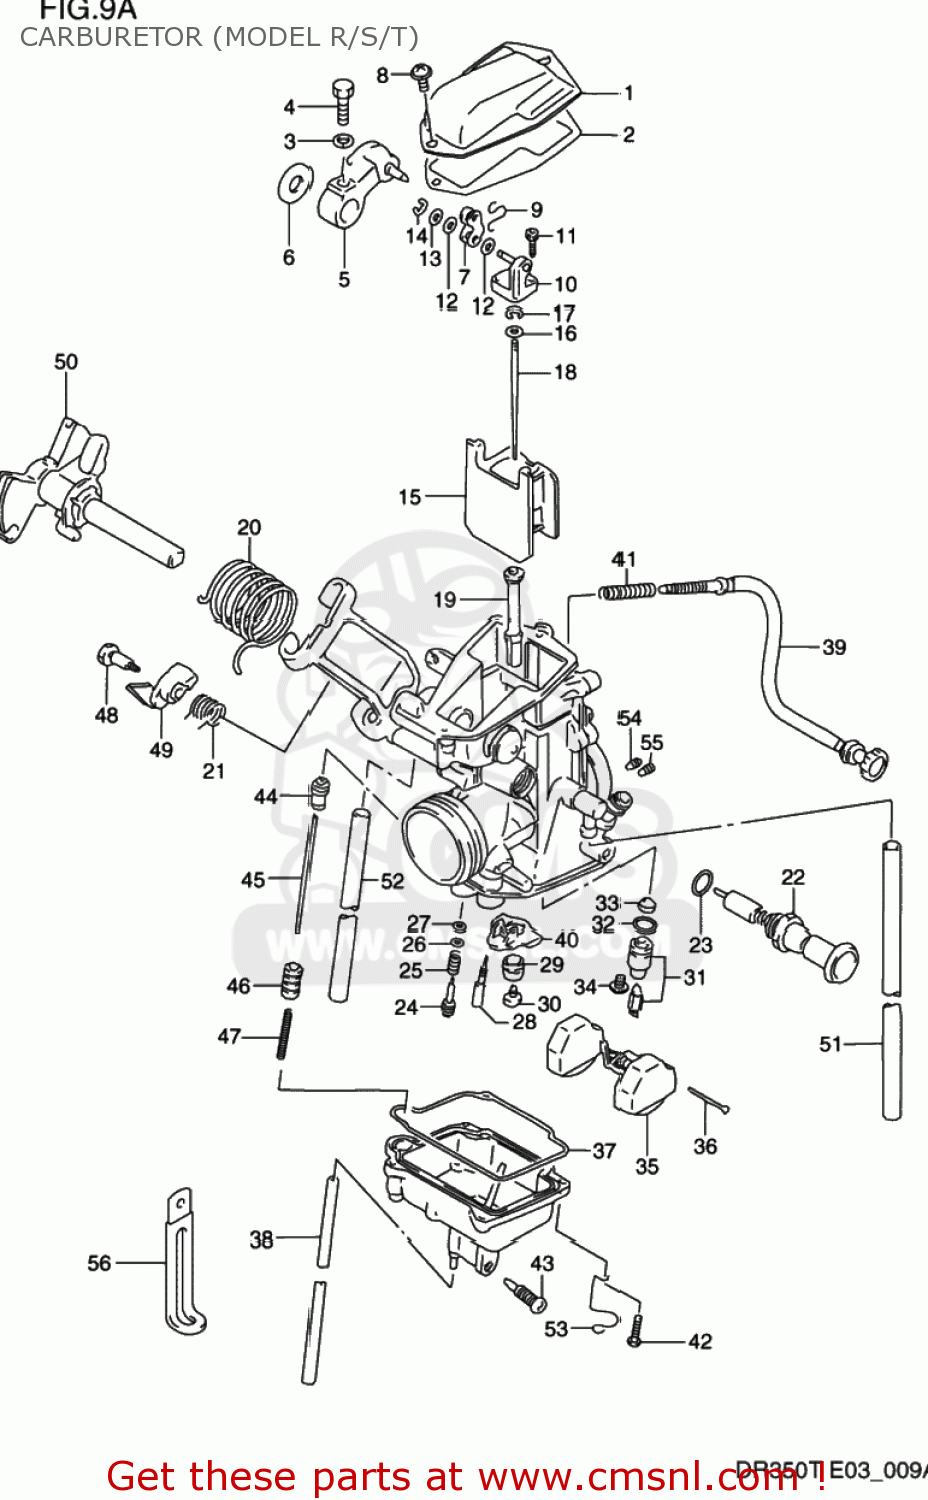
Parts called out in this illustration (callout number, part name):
1	COVER,CARBURETOR,TOP
2	GASKET,CARBURETOR TOP (NAS)
3	LOCK,WASHER
4	BOLT
5	ARM,THROTTLE
6	RING,THROTTLE SHAFT
7	PLATE
8	SCREW
9	SPRING
10	CONNECTOR
11	SCREW
12	GASKET (NAS)
13	WASHER
14	E-RING
15	VALVE,PISTON
16	WASHER,JET NEEDLE
17	CLIP
18	NEEDLE,JET
19	JET,NEEDLE(P-8)
20	SPRING
21	SPRING
22	PLUNGER ASSY
23	O RING
24	SCREW,PILOT
25	SPRING
26	WASHER
27	O RING,PILOT AIR SCREW
28	JET,PILOT(37.5)
29	RING,MAIN JET FIXING
30	JET,MAIN(127.5)
31	VALVE ASSEMBLY,NEEDLE
32	O-RING,NEEDLE VALVE
33	FILTER
34	SCREW
35	FLOAT
36	PIN,FLOAT
37	O RING,FLOAT CHAMBER
38	HOSE(3X5X600)
39	ADJUSTER ASSY
40	RING
41	SPRING
42	SCREW
43	SCREW,DRAIN
44	BOOT, ACCELE PUMP ROD
45	ROD
46	PLUNGER
47	SPRING
48	BOLT
49	LEVER
50	SHAFT ASSEMBLY
51	HOSE(5X9X600)
52	HOSE(5X9X600)
53	CLIP
54	JET,MAIN AIR(0.7)
55	JET,AIR(1.1)
56	CLAMP
